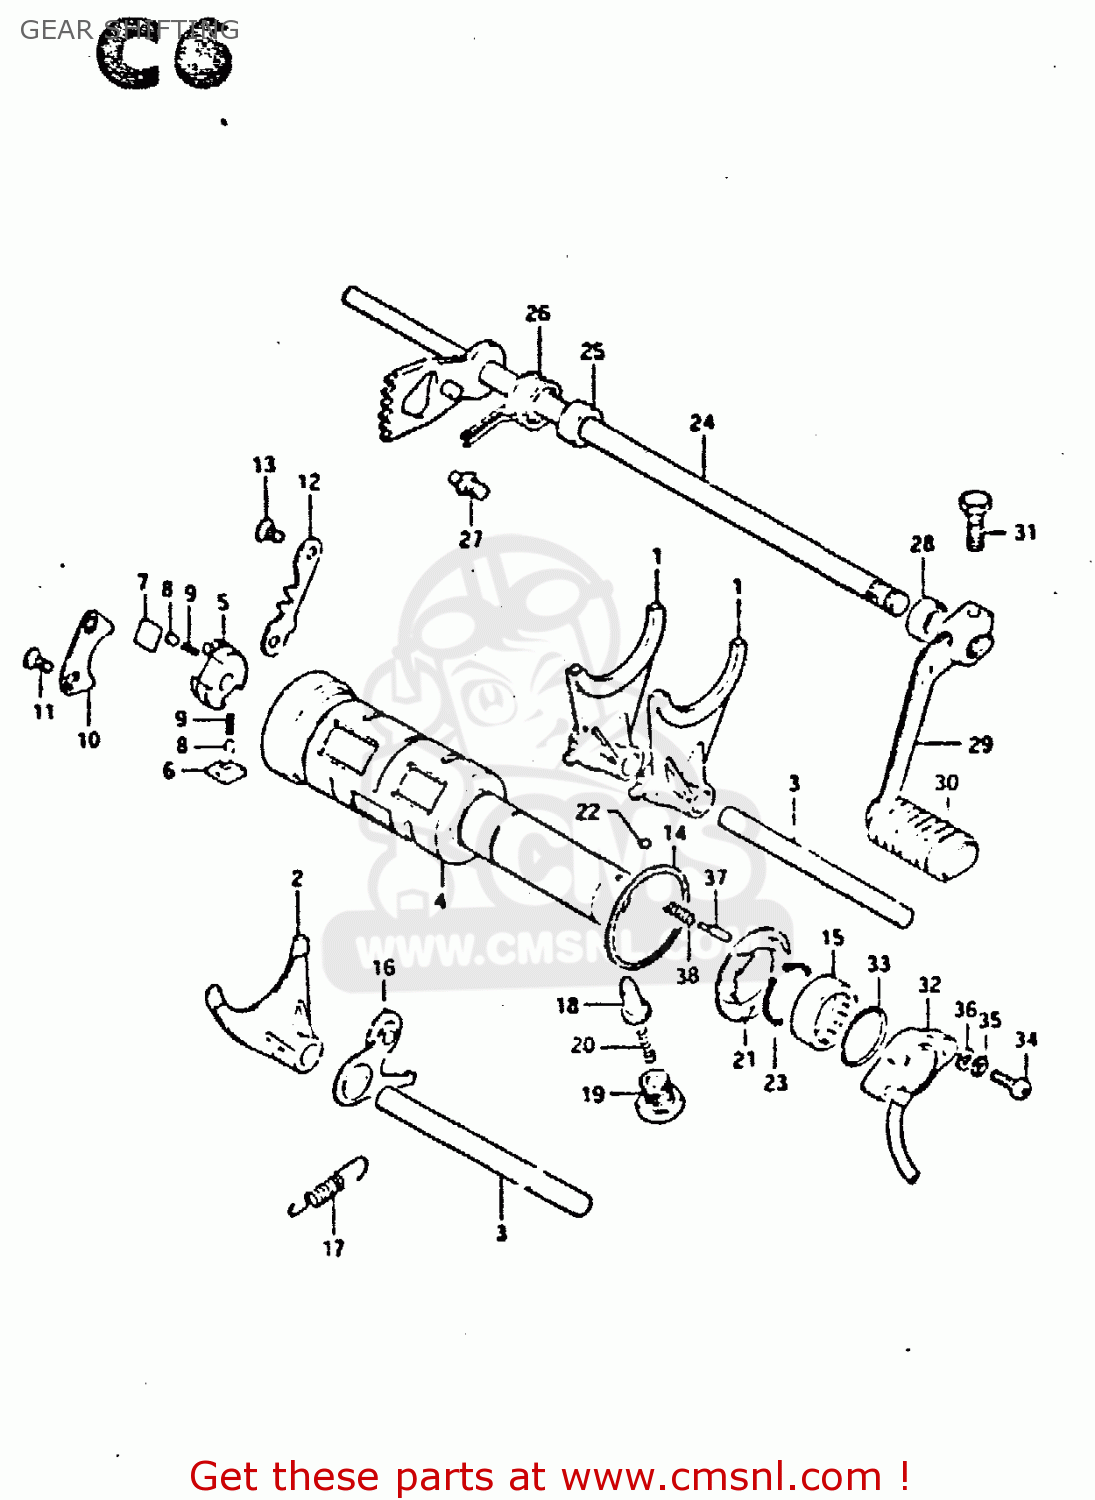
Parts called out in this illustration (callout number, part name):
1	FORK,GEAR SHIFT NO.1
2	FORK,GEAR SHIFT NO.3
3	SHAFT,GEAR SHIFT FORK
4	CAM,GEAR SHIFT
5	GEAR,GEARSHIFT CAM DRIVE
6	PAWL,GEAR SHIFT NO.1
7	PAWL,GEAR SHIFT NO.2
8	PIN(5X8)
9	SPRING
10	LIFTER,GEAR SHIFT PAWL
11	SCREW
12	GUIDE,GEAR SHIFT
13	SCREW
14	WASHER(40X45X1)
15	BEARING(25X32X12)
16	STOPPER,GEAR SHIFTING
17	SPRING
18	STOPPER,GEAR SHIFT CAM NO.2
19	HOLDER,GEAR SHIFT CAM STOP SPR
20	SPRING
21	PLATE,GEAR SHIFT CAM STOPPER
22	PIN 4X6
23	CIRCLIP,25MM
24	SHAFT,GEAR SHIFT
25	SPACER(12X20X15.3)
26	SPRING
27	STOPPER,GEAR SHIFT CAM
28	OIL SEAL
29	LEVER ASSEMBLY,GEAR SHIFTING
30	RUBBER,PEDAL
31	BOLT
32	TERMINAL BASE ASSY,GEAR SHIFT
33	O-RING (D:2.4 ID:26.2)
34	SCREW 5X20
35	LOCK WASHER
36	WASHER
37	PIN(5X15.5)
38	SPRING
